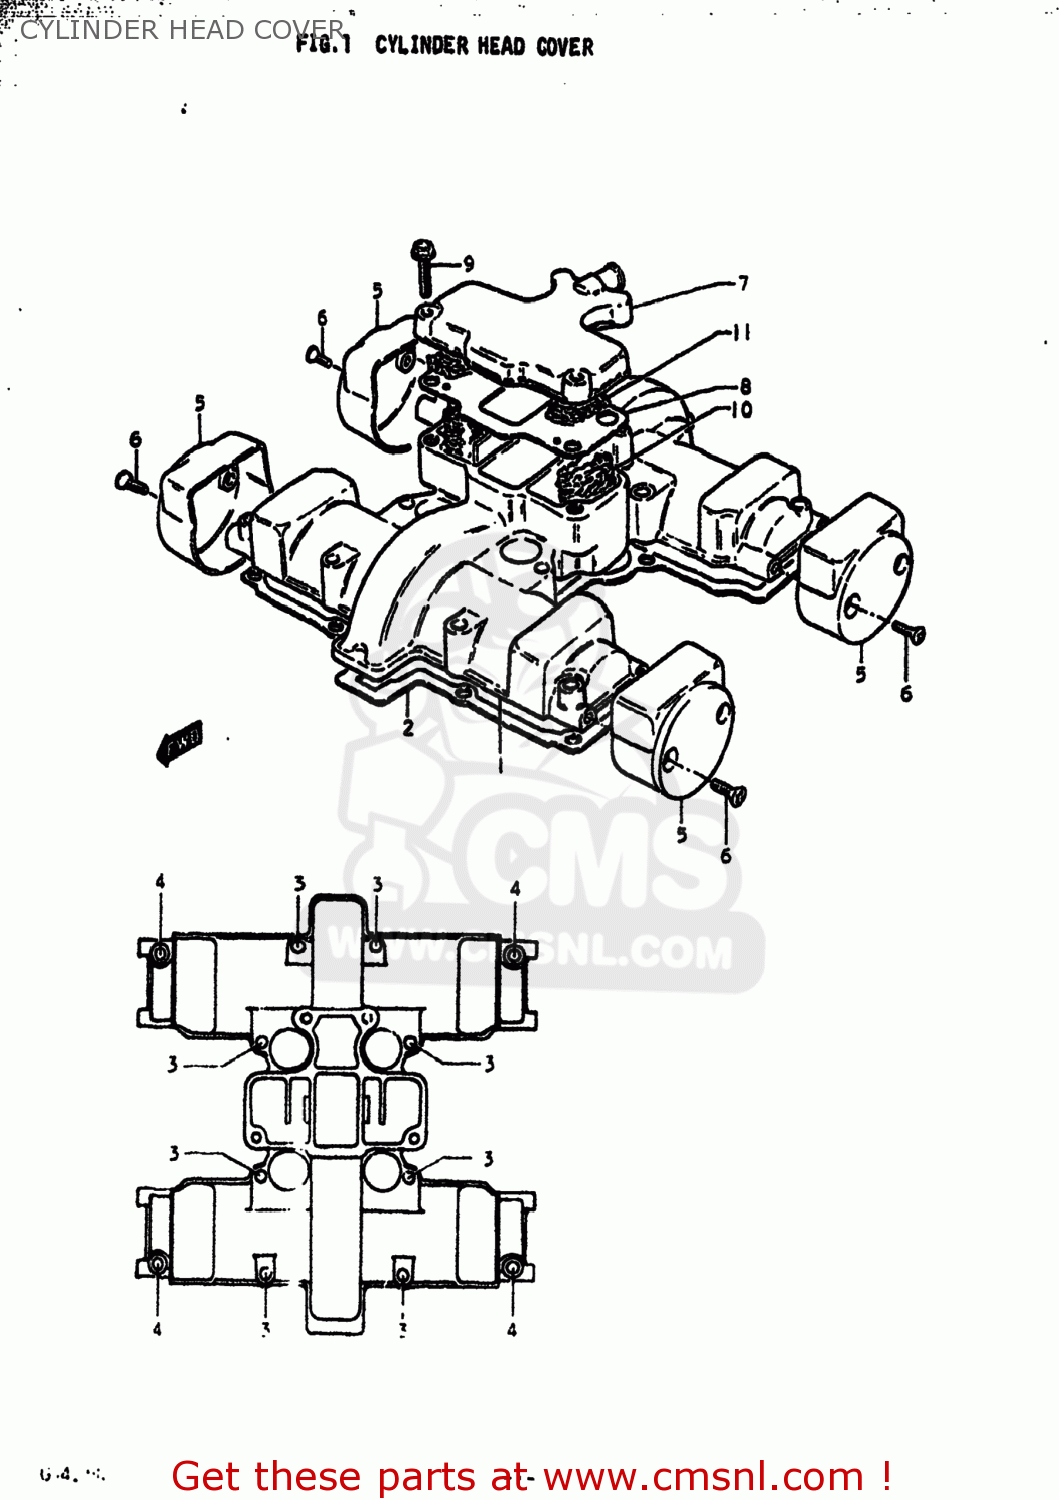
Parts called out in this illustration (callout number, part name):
1	COVER,CYLINDER HEAD
2	GASKET,CYLINDER HEAD COVER (MCA)
3	BOLT
4	BOLT
5	CAP,CYLINDER HEAD COVER
6	SCREW
7	COVER,BREATHER
8	GASKET (MCA)
9	BOLT
10	COVER,BREATHER
11	SEPARATOR,OIL BREATHER
